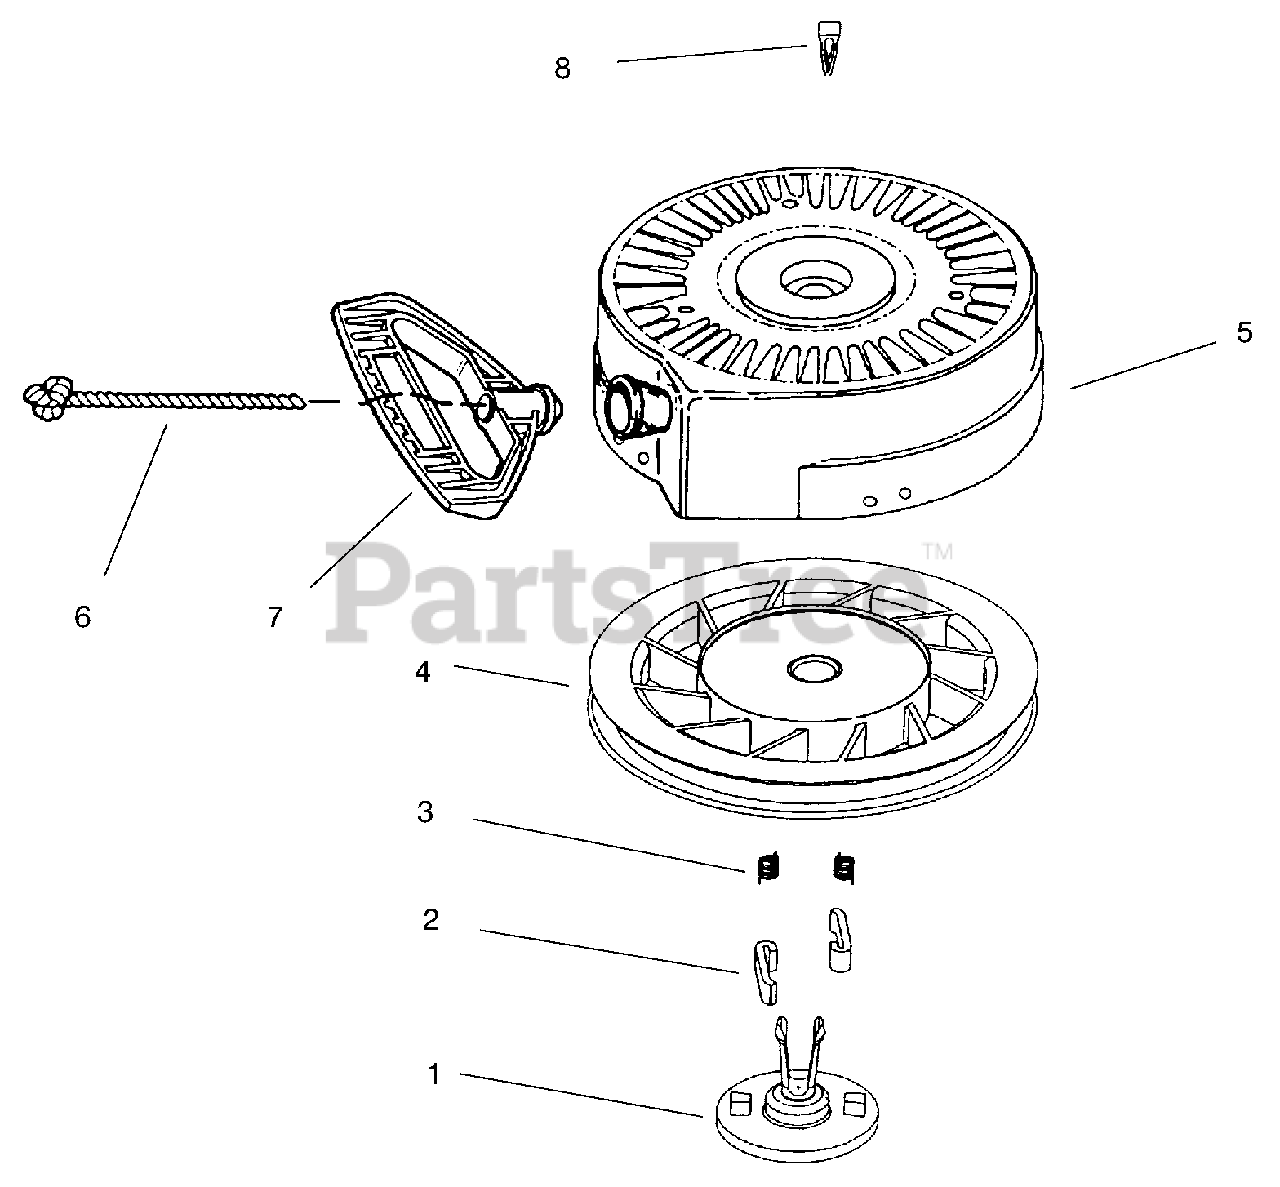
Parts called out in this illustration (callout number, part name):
1	Retainer
2	Starter Dog
3	Dog Spring
4	Pulley & Rewind Spring Asm.
5	Starter Housing Asm.
6	Starter Rope
7	Mitten Grip Handle
8	Locking Tab
